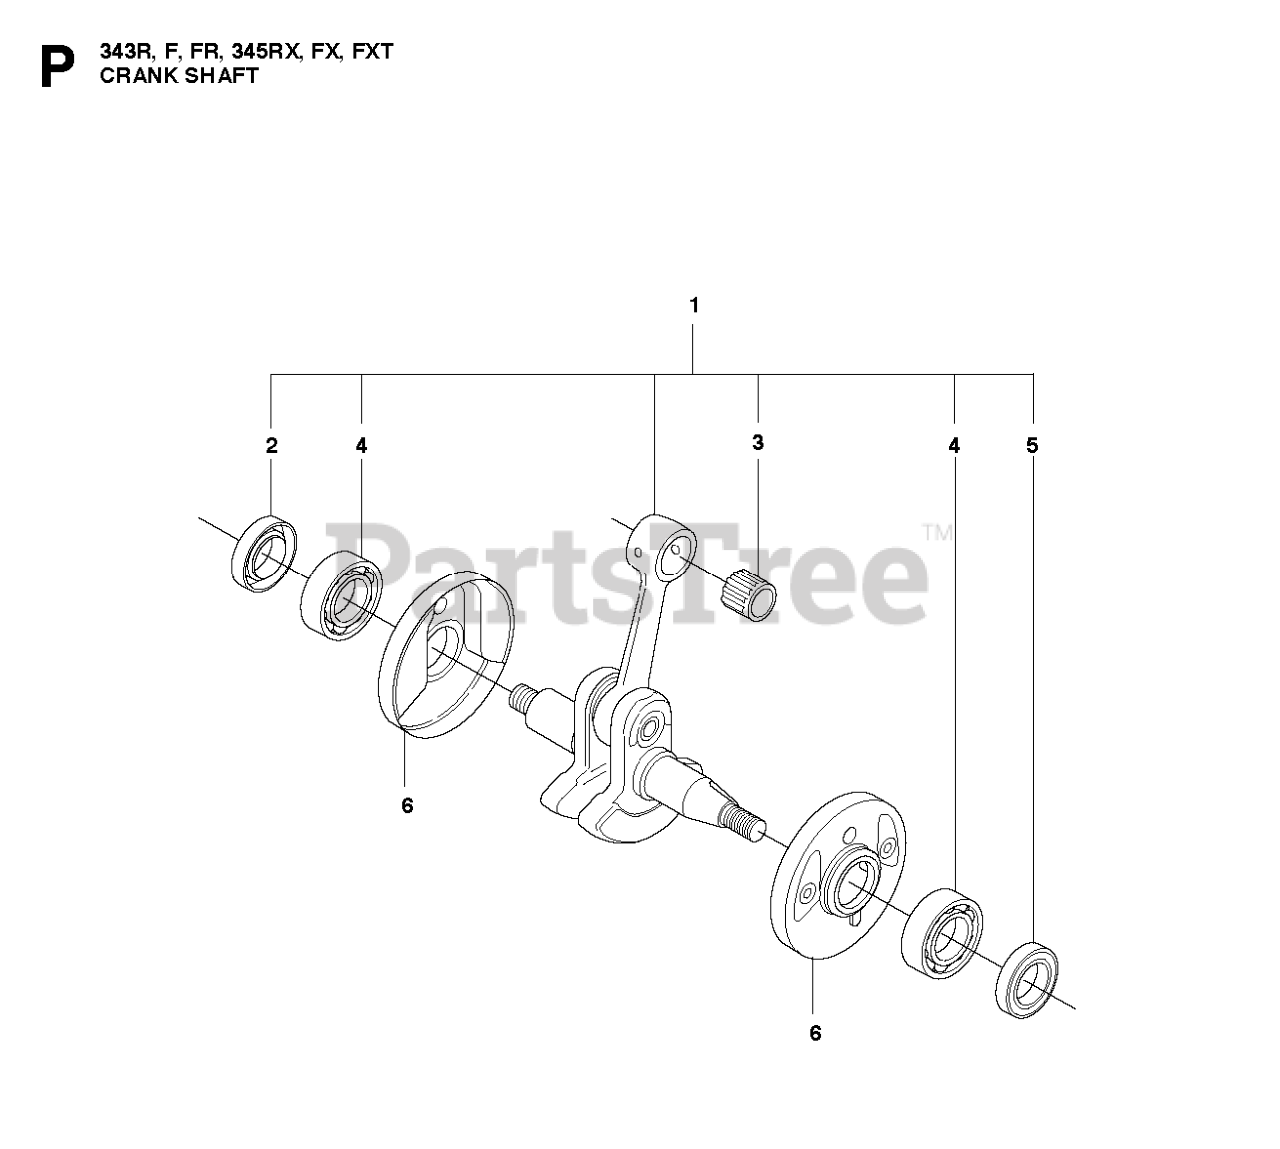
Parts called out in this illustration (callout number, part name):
1	CRANKSHAFT
2	SEALING RING
3	SUPPORT BUSHING
4	BALL BEARING
6	COLLAR
